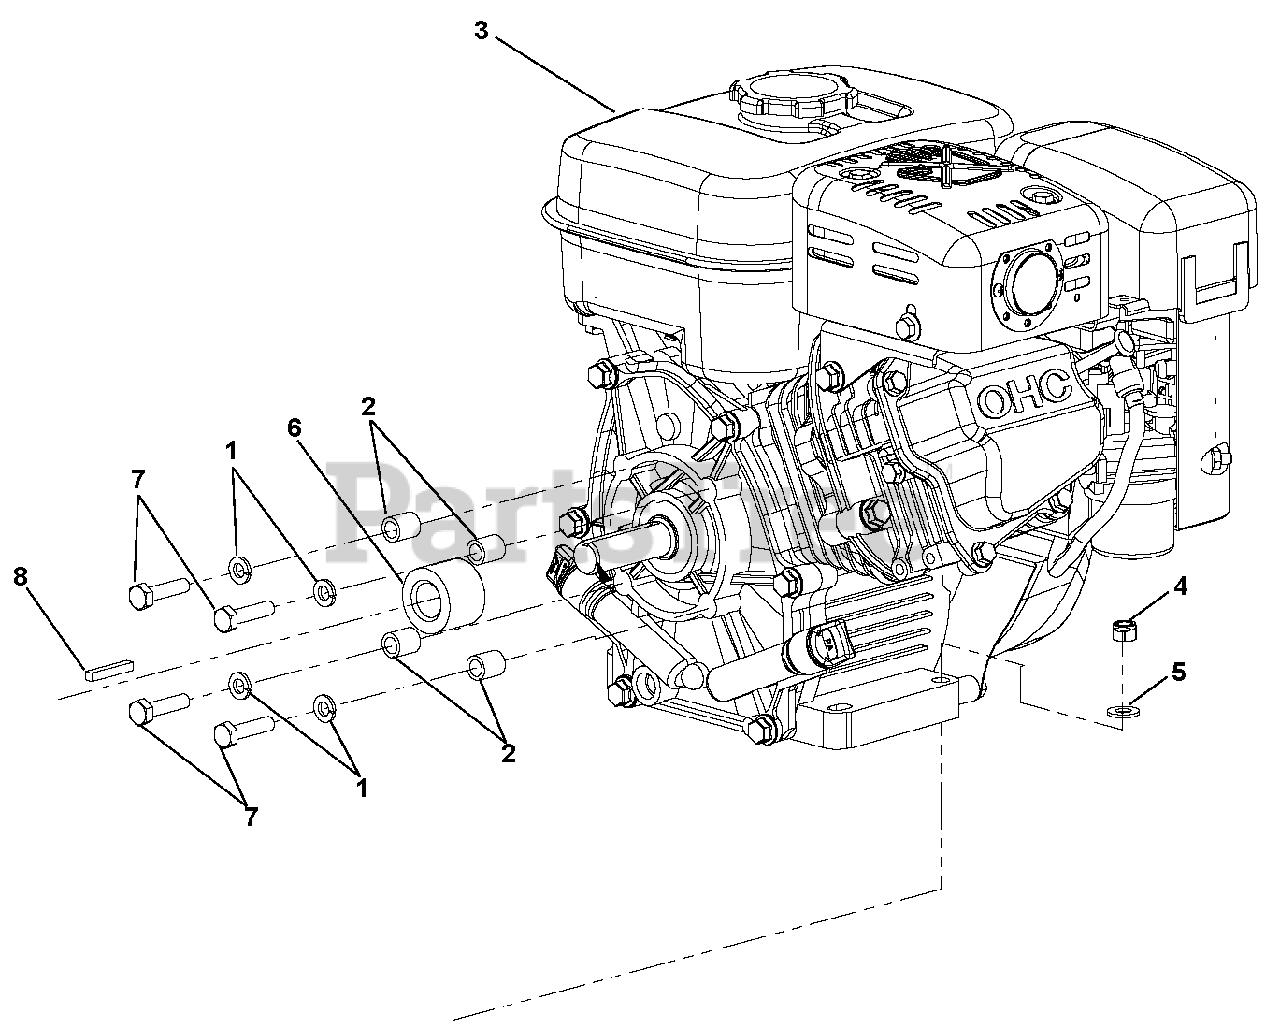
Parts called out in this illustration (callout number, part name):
1	Washer, Flat Steel .344 x .688 x .065
2	Spacer, Engine Blower Housing
3	Engine, Subaru 6HP
4	Nut, Locking, Nylon 5/16-18
5	Washer, Flat Steel .344 x .688 x .065
6	Engine Fan Spacer
7	Bolt, Hex .31-24 x 1.25
8	Key 3/16" x 1 1/4"
